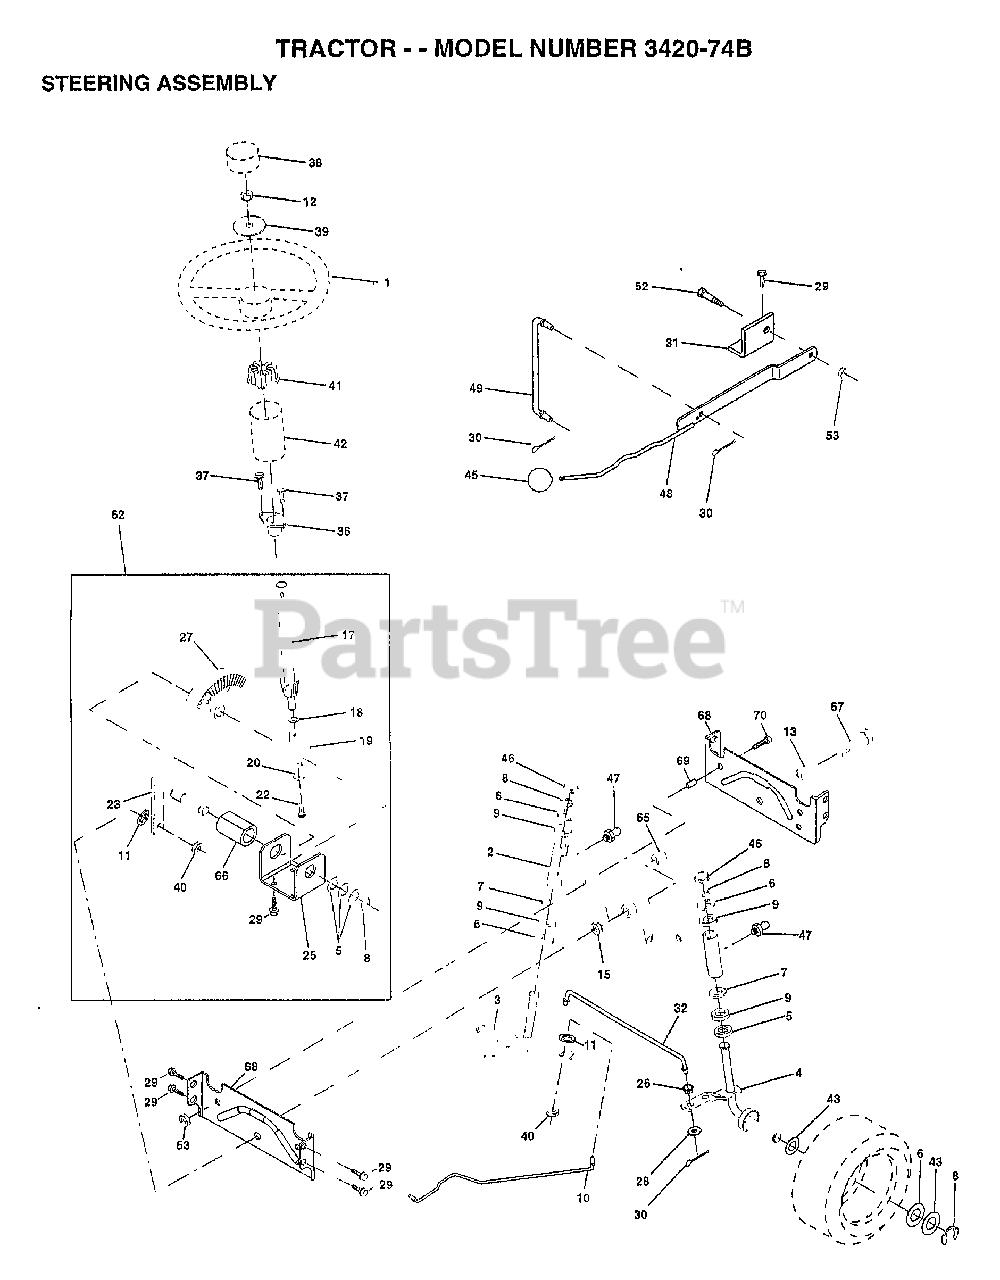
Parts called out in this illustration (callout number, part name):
2	AXLE ASM
3	SPINDLE.ASM.LH
4	"SPINDLE ASM,RH"
5	WASHER .T
6	WASHER
7	WASHER
9	COL. SRTG. BEAR.
10	DRAGLINK-STAMPED
11	LOCKWASHER
13	BEARING AXLE
15	"NUT-LOC,FLANGE LT"
17	SHAFT ASM STEERNG
18	THRUST WASHER
19	SUPPORT.SHAFT
22	SCREW HEX SOC1/4-
25	BRKT-STEERING
26	BUSHING.DRAGLINK
27	GEAR SECTOR
28	WASHER
29	SCREW
30	COTTER PIN
32	TIE ROD
36	BUSHING.STRG.3/4
37	"SCREW-TT,10-32 FL"
38	"INSERT,STR WHEEL"
39	WASHER
40	GRIPCO NUT
41	ADAPTER LT
43	WASHER
46	CAP
47	ZERK M
62	KIT STEERING ASM
65	SPACER AXLE
66	"BEARING-ARM,PITMA"
67	BOLT
68	BRACE AXLE
69	"SPACER BRCAE,AXLE"
70	BOLT.HEX.3/8-16X2
